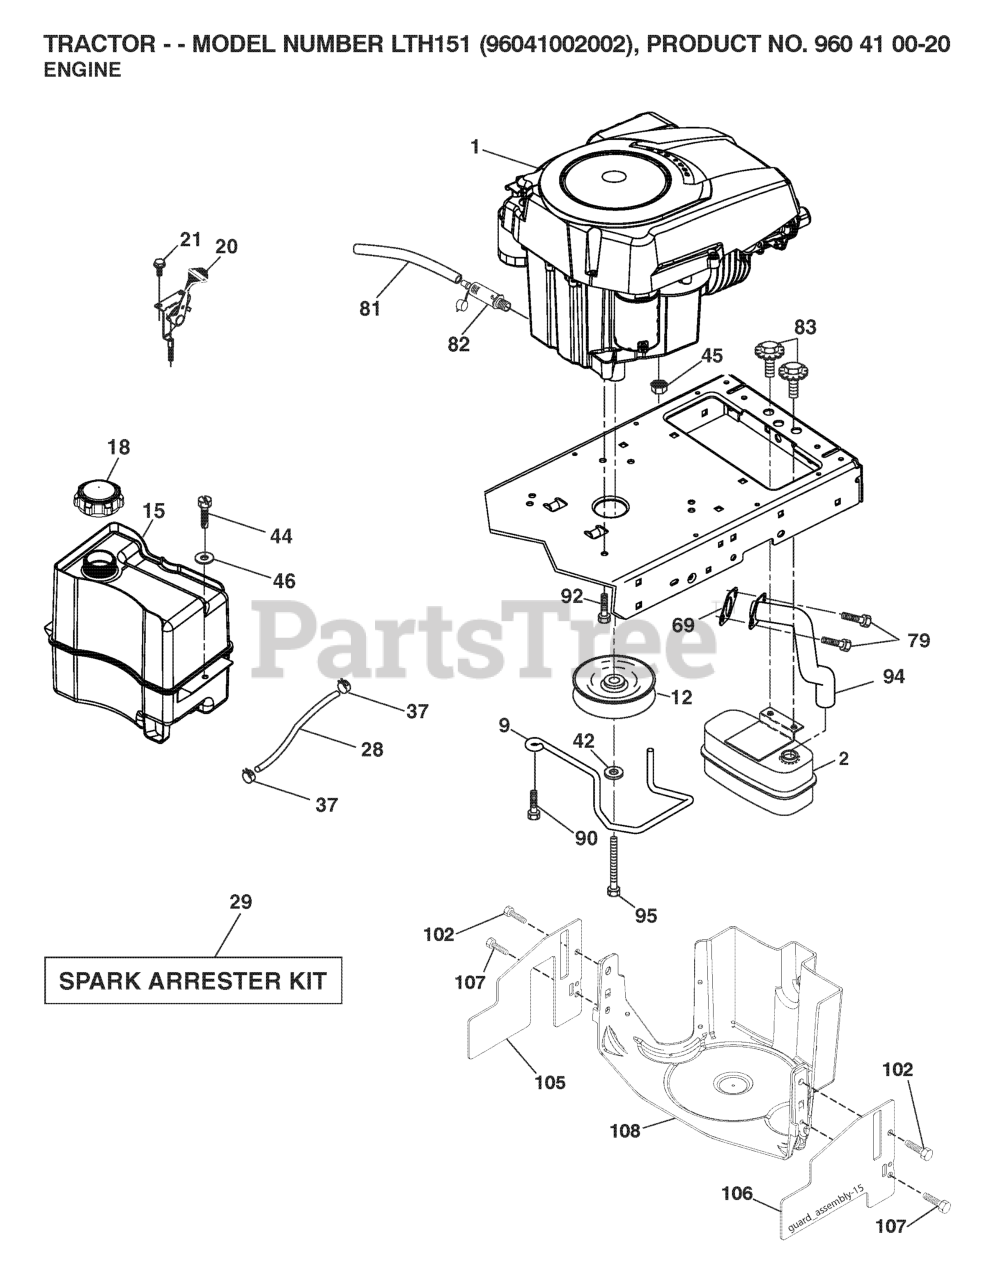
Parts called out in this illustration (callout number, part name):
2	MUFFLER.SINGLE.CYL.KOHL/B&S
9	KEEPER.BELT.ENGINE.4.2
12	PULLY ENGINE
15	RP TANK FUEL FRT 1.5 GAL
18	FUEL CAP
20	CONTROL.TH/CK.C.
21	SCREW
28	LINE.FUEL.20
29	KIT.SPARK ARRESTOR 794945 B&S
37	HOSE CLAMP
42	LOCKWASHER
44	SCREW HEXWSHR 1/4-20X3/4
45	NUT
69	GASKET.EXHAUST.KOHLER
79	SCREW.SOCKET HD.5/16-1
81	TUBE, DRAIN OIL ASM.
82	PLUG DRAIN OIL EASY
83	BOLT.5/16-18UNCX3/4 W/SEMS.BLK
90	SCREW 3/8-16X1
92	SCREW 3/8-16X1
94	RP.TUBE.EXHAUST.KOHL.COURAGE
95	BOLT HEX 7/16-20X4-1/4"
102	SCREW
105	SHIELD.SIDE.LH.3842"TEX FRENCH
106	SHIELD.SIDE.RH.3842"TEX FRENCH
107	SCREW.1/4-20X5/8
